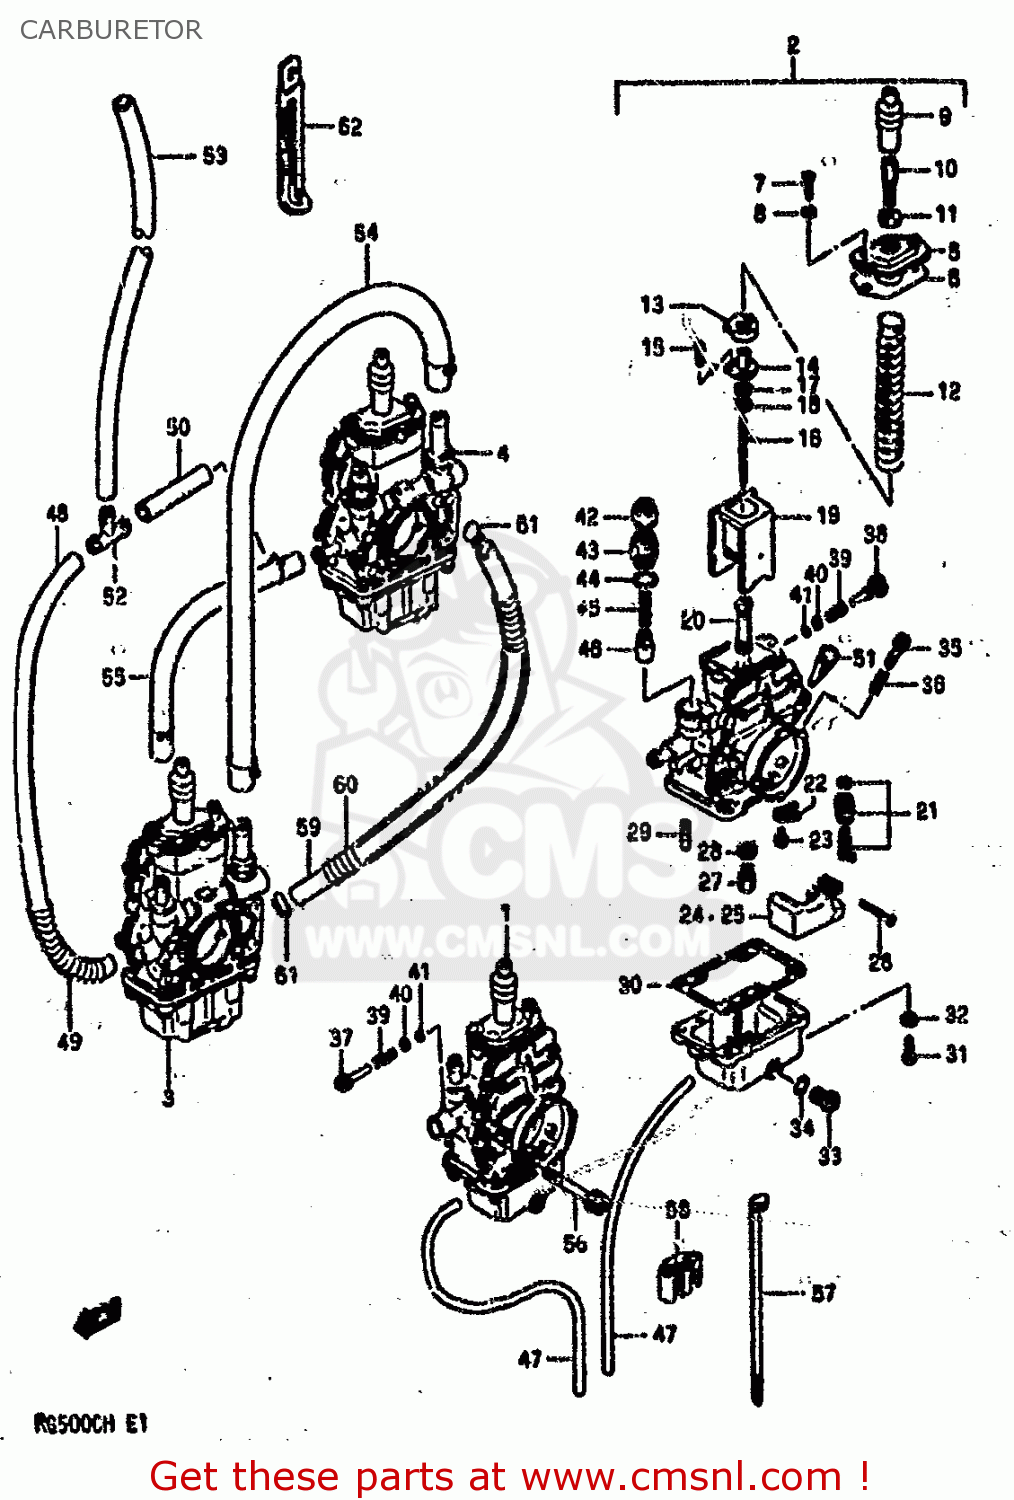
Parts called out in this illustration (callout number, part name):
1	CARBURETOR ASSY,FRONT LH
2	CARBURETOR ASSY,REAR LH
3	CARBURETOR ASSY,FRONT RH
4	CARBURETOR ASSY,REAR RH
5	CAP,CARBURETOR TOP
6	GASKET (NAS)
7	SCREW
8	LOCK WASHER
9	CAP,CABLE ADJUSTER
10	ADJUSTER,CABLE
11	NUT
12	SPRING
13	RING
14	JOINT
15	SCREW
16	NEEDLE,JET
17	WASHER,JET NEEDLE
18	CLIP
19	VALVE,PISTON
20	JET,NEEDLE (P-5)
21	VALVE ASSY,NEEDLE
22	PLATE
23	SCREW
24	FLOAT
25	FLOAT
26	PIN,FLOAT
27	JET,MAIN(120)
28	WASHER,NEEDLE NOZZLE
29	JET,PILOT(25)
30	GASKET (NAS)
31	SCREW
32	LOCK WASHER
33	PLUG
34	GASKET,DRAIN,PLUG (NAS)
35	SCREW,AIR
36	SPRING
37	SCREW,THROTTLE STOP
38	ADJUSTER,THROTTLE STOP
39	SPRING
40	WASHER
41	O RING
42	CAP
43	HOLDER,GUIDE
44	O RING
45	SPRING
46	PLUNGER,STARTER
47	HOSE SET (3X5X525)
48	HOSE (3X5X125)
49	SPRING
50	HOSE
51	FILTER
52	JOINT,3 WAY
53	HOSE
54	HOSE SET (8X13X250)
55	HOSE SET (6.5X11.5X115)
56	BOLT
57	CLAMP
58	CLIP
59	HOSE (4X11.4X150)
60	SPRING
61	CLIP
62	CLAMP
